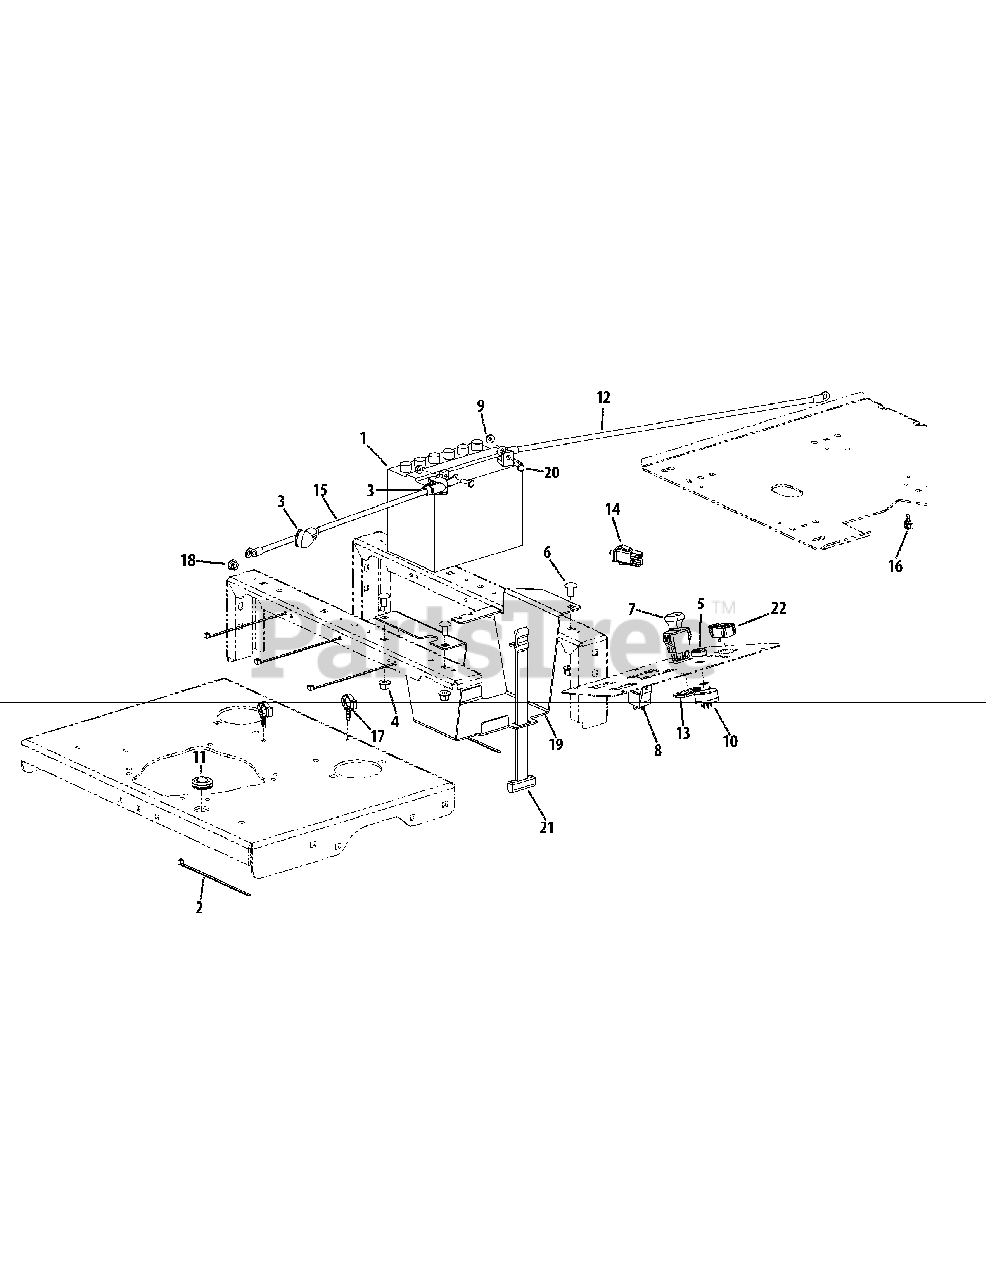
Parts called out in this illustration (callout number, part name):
2	Cable Tie
3	Boot Terminal, 1.00 x 2.50
4	Flange Counter Lock, 3/8-16
5	Ingnition Nut w/ Cap, 5/8-32
6	Carriage Bolt, 3/8-16 x .75
7	PTO Switch
9	Flange Top Lock Nut, 1/4-20
10	Ignition Switch
11	Grommet, .75
12	Batter Cable
13	PTO Switch Bracket
14	Switch
15	Batter Cable
16	Electric CDT Clip, 3/8
17	Electric CDT Clip, 5/8
18	Flange Nut, M8-1.25
19	Battery Bracket
20	Hex Screw, 1/4-20 x .75
21	Battery Strap
22	Hour Meter
